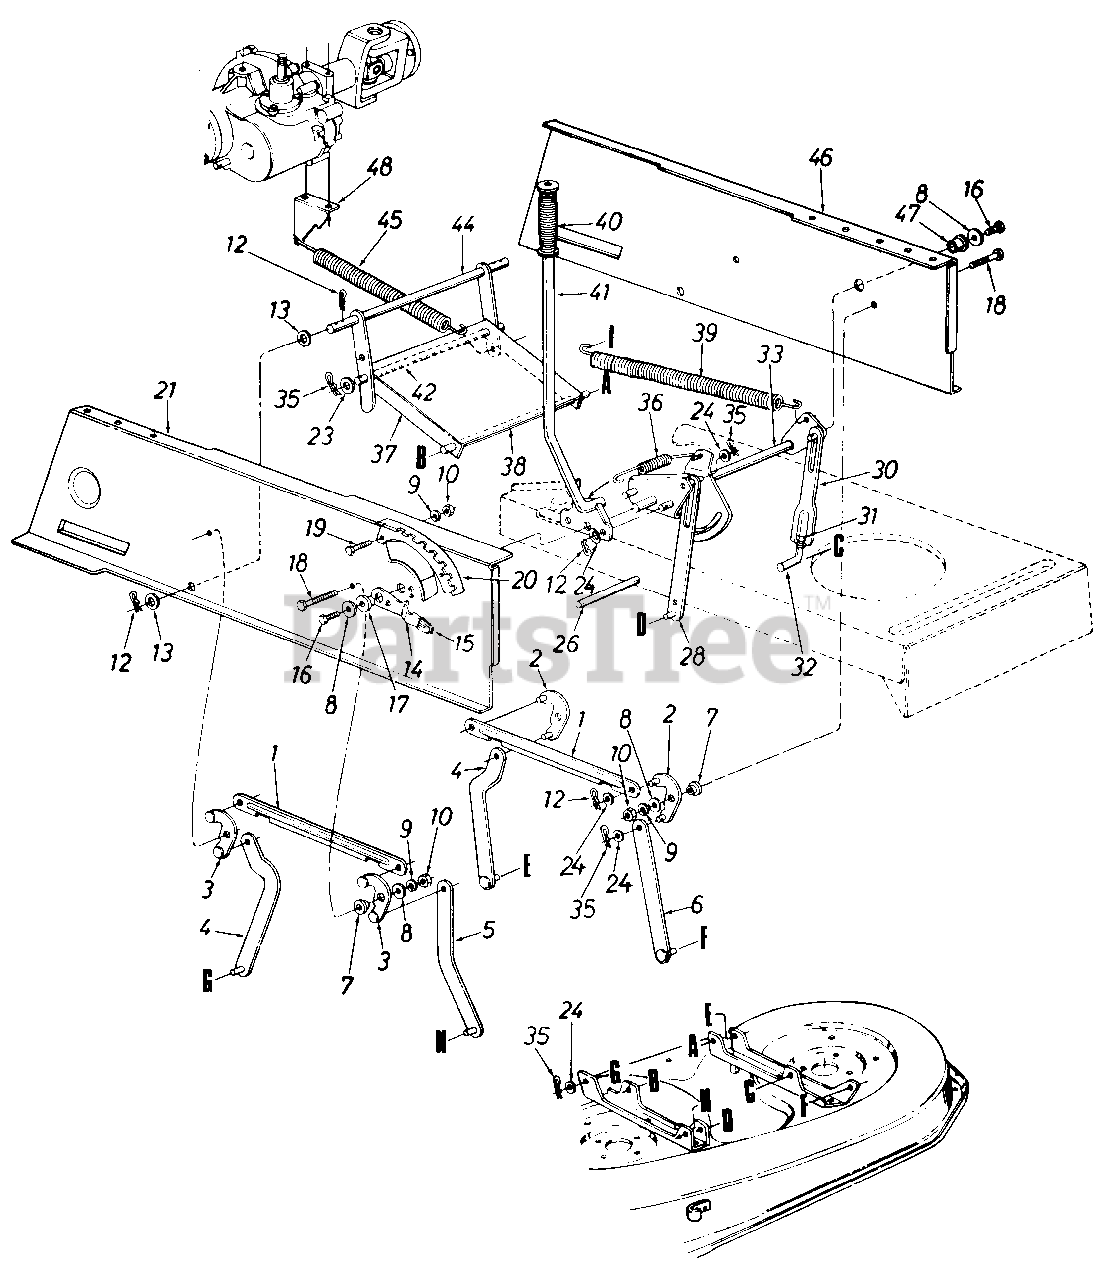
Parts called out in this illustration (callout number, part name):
1	Connecting Rod
2	Pivot Link Ass'y. L.H.
3	Pivot Link Ass'y. R.H.
7	Shld. Spacer .3/8" I.D.
8	Fl-Wash. .344" I.D. x 1.125"
9	L-Wash. 5/16" I.D.
10	Hex Nut 5/16-18 Thd.
12	Cotter Pin 1/8" Dia.
13	Fl-Wash .635" I.D. x 1.0" O.D.
14	I Deck Lift Down Stop
15	Knob
16	Hex Wash. TT-Tap Scr. 5/16-18 x .75" Lg.
17	Flange Brg. .63" I.D.
18	Hex Wash. TT-Tap Scr. 5/16-18 x .875" Lg.
19	Hex Bolt 5/16-18 x .75" Lg.
20	Index Brkt.
21	Upper Frame R.H.
23	Fl-Wash. .385" I.D. x .87" O.D.
24	Fl-Wash. .531" I.D. x .93" O.D.
26	Running Board Rod
31	Hex Jam Nut 1/2-20 Thd. (Grade 5)
32	Lift Link Adjuster
33	Lift Shaft Ass'y.
35	Inter. Cotter Pin 3/8" Dia.
36	Extension Spring
37	Stabilizer Bracket
38	Shaft 1/2" Dia. x 10.28" Lg.
39	Extension Spring
40	Grip
41	Deck Lift Handle Ass'y.
42	Shaft 3/8" Dia. x 9.34" Lg.
44	Stabilizer Shaft Ass'y.
45	Extension Spring 7.58" Lg.
46	Upper Frame L.H.
47	Flange Brg. .632" I.D.
48	Spring Retainer Brkt.
